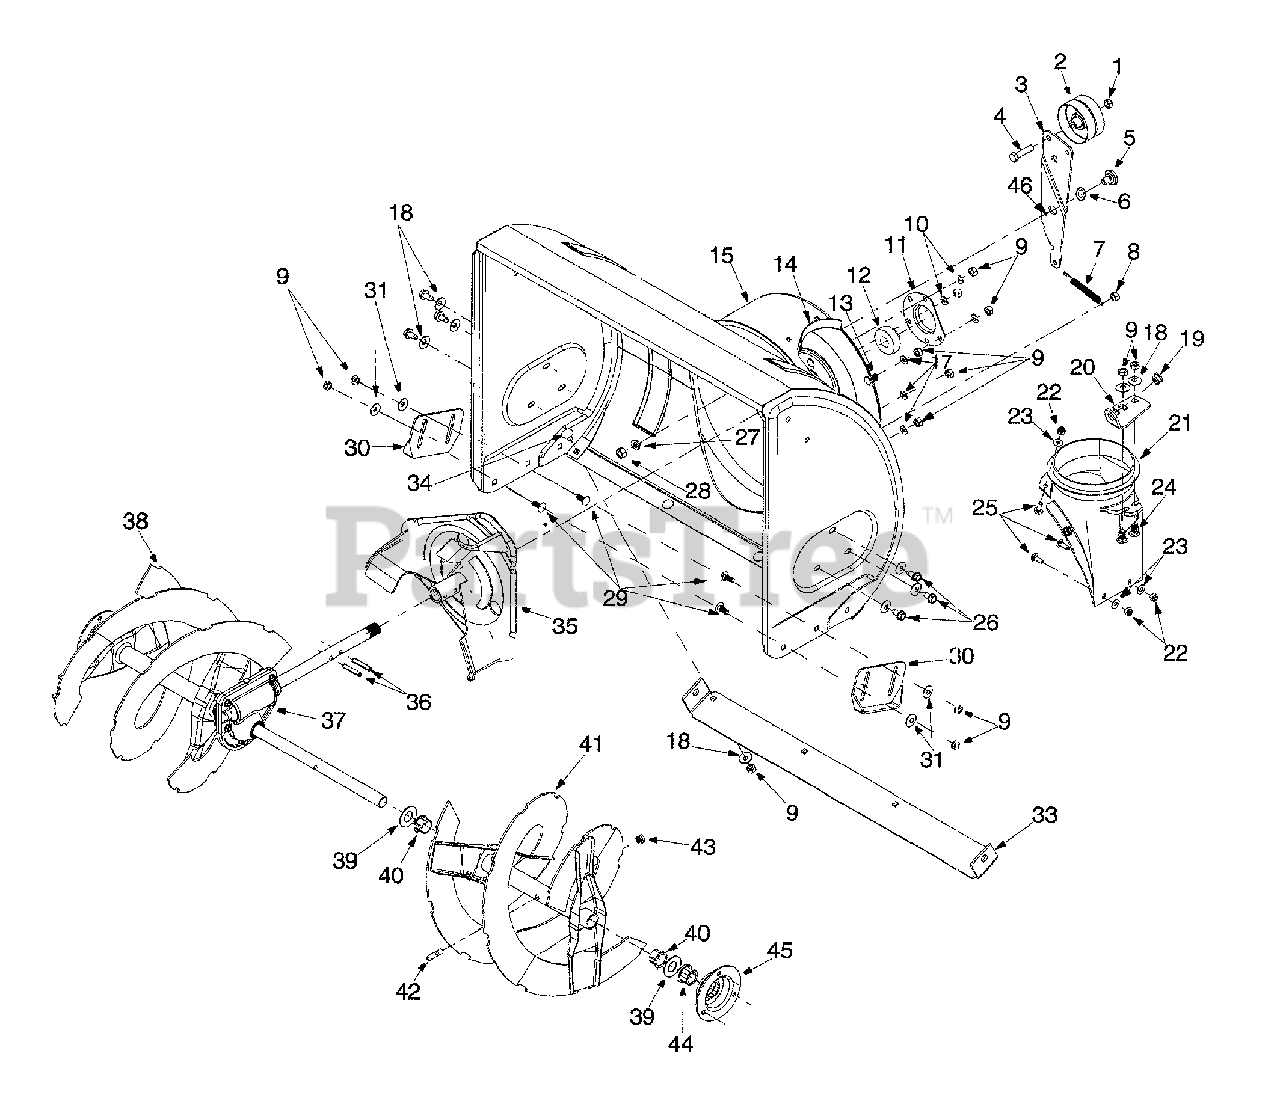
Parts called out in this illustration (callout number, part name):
1	Lock Jam Nut 3 8-24
2	Flat Idler
4	Hex Cap Screw 3/8-24 x 1.50
5	Shoulder Screw
6	Flat Washer
7	Extension Spring
8	Hex Nut 5/16-18
9	Hex Nut 5/16-18
10	Lock Washer 5/16
11	Housing
12	Ball Bearing
13	Carriage Bolt 5/16-18
18	Bell Washer
19	Bushing
21	Chute Adapter
22	Hex Lock Nut 1/4-20
23	Flat Washer
24	Carriage Bolt
25	Carriage Screw 1/4-20 x .75
26	Hex Washer crew 5 16-18
27	Lock Washer 3/8
28	Hex Nut 3/8-16
29	Carriage Bolt 5/16-18 x .75
31	Bell Washer
34	Carriage Bolt 5/16-18 x .62
37	22" Gear Assembly
40	Flange Bushing
42	Shear Bolt 5/16-18 x 1.5
43	Lock Nut 5/16-18
44	Hex Flange Bearing
46	Grease
